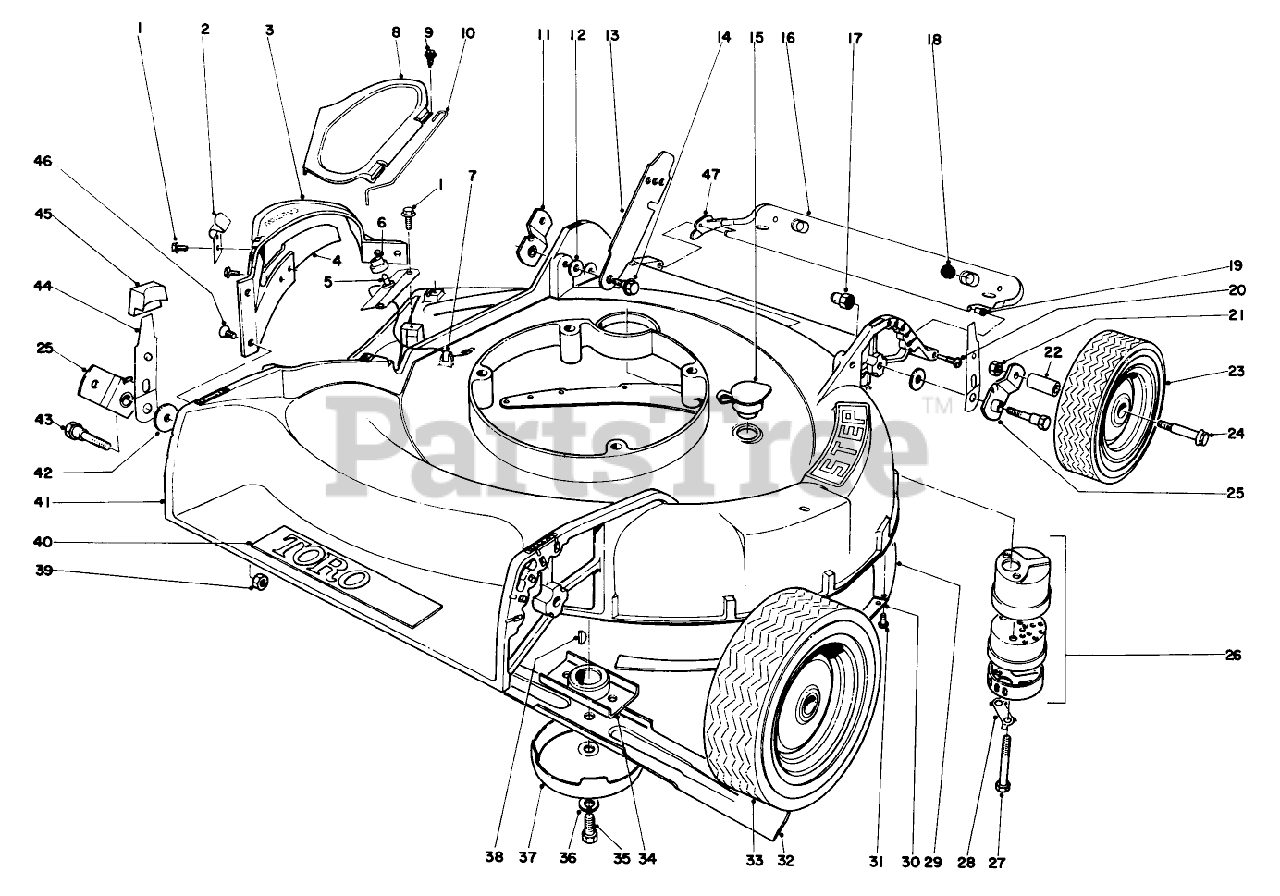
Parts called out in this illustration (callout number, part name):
3	Deflector (Incl. Ref. Nos. 1-4)
4	DefIector Bar
8	Deflector Cover (Incl. Ref. Nos. 11 12)
9	SCREW
10	Hinge Spring
12	SPACER
14	SCREW-SHOULDER
15	WASHOUT PLUG
17	HANDLE PIVOT NUT
26	MUFFLER ASM
27	SCREW-HH
28	CLIP - LOCKING
30	Secondary Skirt
36	WASHER-LOCK
38	KEY-WOODRUFF
40	Toro Emblem
41	Housing (Incl. Ref. #29, 30 31)
42	WASHER-PIVOT
43	5/16-18 PIVOT SCREW
